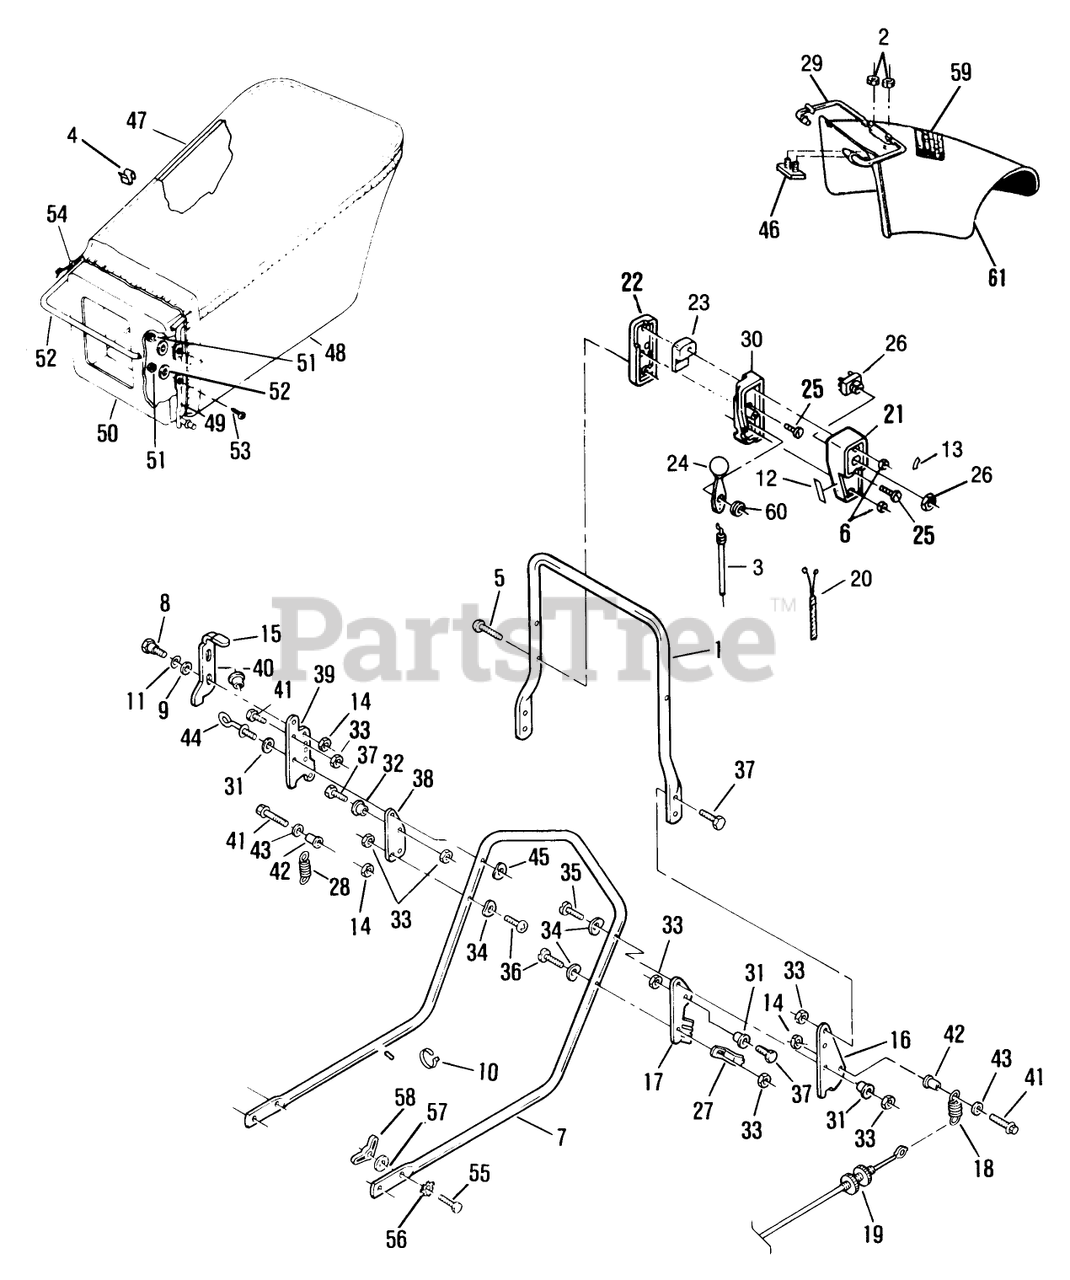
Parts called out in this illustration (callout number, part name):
2	LOCKNUT E
3	T/CABLE WESCON
4	S CLIP ARDEN
5	SCREW
6	NUT C/LOCK E
7	HANDLE SECTION
8	BOLT RB&W
9	WASHER M
14	LOCKNUT E
15	KNOB (S&R)
18	SPRING
19	CABLE AY
22	OUTER CONTROL CASE
24	LEVER&KNOB AY WES
25	SCREW
29	LATCH BAR ARGO
33	NUT-LOCK F
34	WASHER-CURVED
35	SCREW LARSON
42	SPACER ROCKFORD
43	WASHER
47	HANGER BAG TROX
50	BAG ADAPTOR PL
51	LOCKNUT E
52	WASHER
57	WASHER
58	NUT-WING
60	WASHER-SPRING
